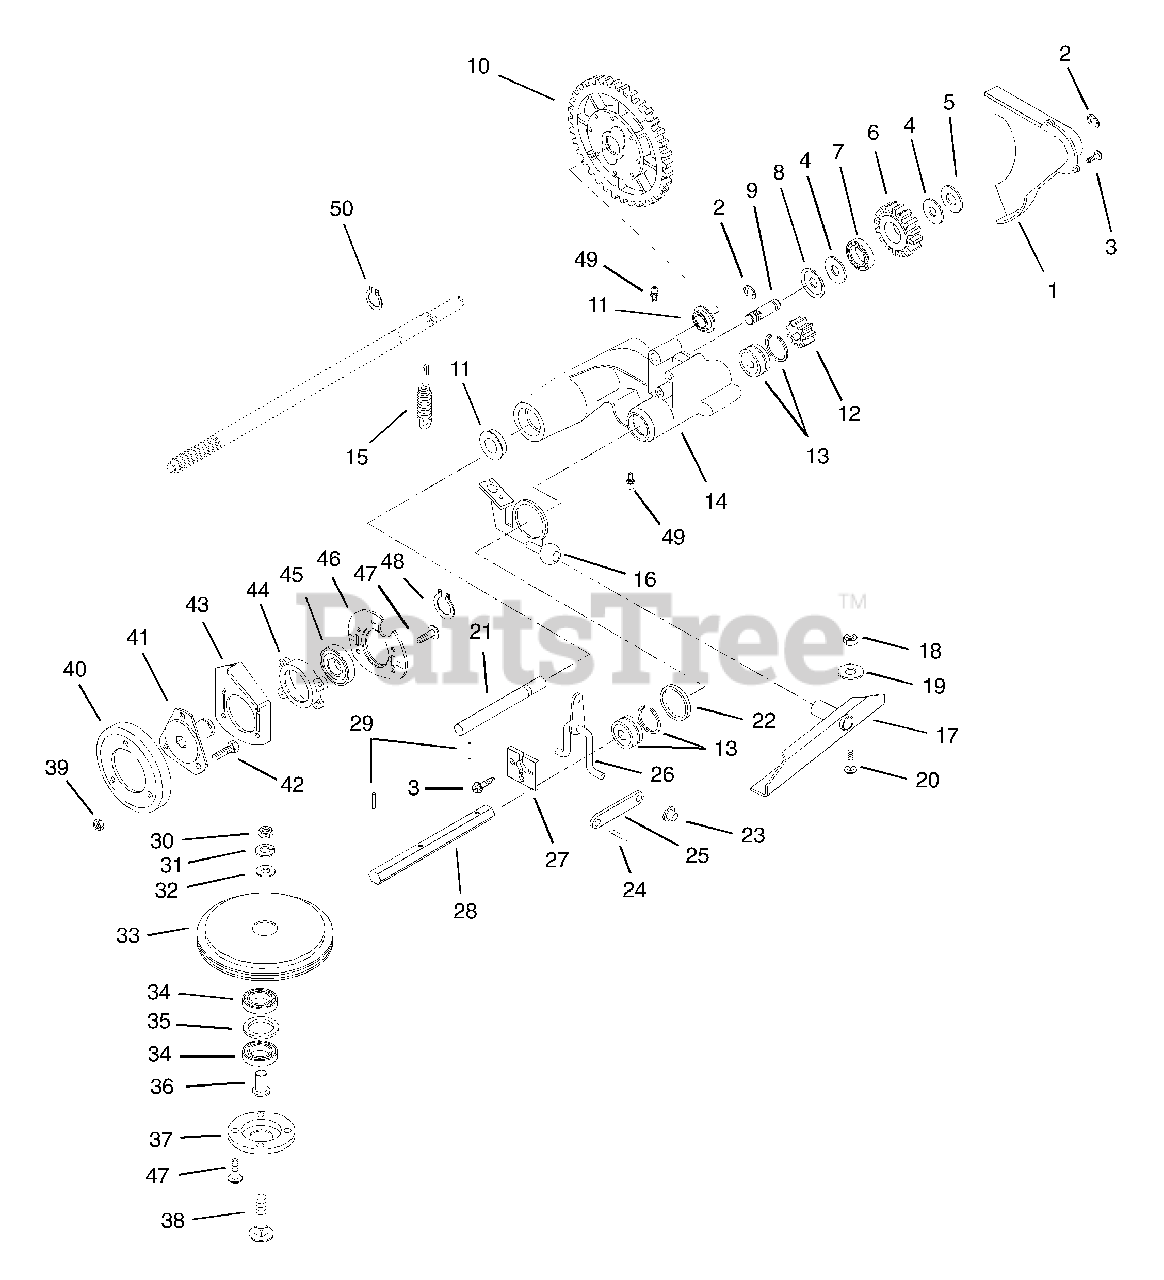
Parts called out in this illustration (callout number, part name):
1	Gear Cover
2	Ring-Retaining-External .438 x .035
3	Screw-Tapping 12-24 x .50 Hex Washer Head
4	Washer - Flat - Steel .520 x .875 x .062
5	Washer - Flat - Steel .531 x 1.00 x .063
6	Idler Gear
7	Bearing - Ball .50 x 1.38 x .437
8	Retainer
9	Idler Shaft
10	Differential Assembly
11	Bearing-Ball .625 x 1.38 x .50
12	Gear - Pinion
13	Bearing - Ball .562 x 1.375 x .437
14	Drive Mount
15	Spring - Tension .051 x .60 x 2.25
16	Drive Actuator Weldment
17	Pivot Channel Weldment
18	Nut - Locking - Center .31-18
19	Washer-Flat-Steel .344 x .688 x .065
20	Bolt-Round Head Square Neck .31-18 x .62
21	Rod - Guide
22	Washer - Flat - Steel 1.390 x 2.00 x .02
23	Push Nut, .25
24	Pin - Roll .125 x .63
25	Shift Link
26	Shift Arm Weldment
27	Retainer Plate
28	Hex Shaft
29	Pin - Roll .125 x .50
30	Nut - Hex .31-18
31	Washer - Locking .312 x .097 Heavy
32	Washer - Flat - Steel .328 x .875 x .062
33	Friction Sheave
34	Bearing - Ball .625 x 1.375 x .43
35	Washer - Flat - Steel 1.062 x 1.344 x .032
36	Spindle Bearing
37	Bearing Retainer
38	Bolt - Round Head Square Neck .31-18 x 1.75 Grade 5
39	Nut - Locking - Center .25-20
40	Disc, Friction
41	Friction Wheel Hub
42	Bolt - Hex .25-20 x .50 Grade 5
43	Bearing Plate
44	Bearing Retainer
45	Bearing Ball 1.00 x 2.00 x .56
46	Bearing Retainer
47	Screw - Tapping 12-24 x .50 Hex Washer Head
48	Ring - Retaining - External 1.00 x .042
49	Fitting - Lube .25-28 x .256
50	Ring - Retaining - External .625 x .035
